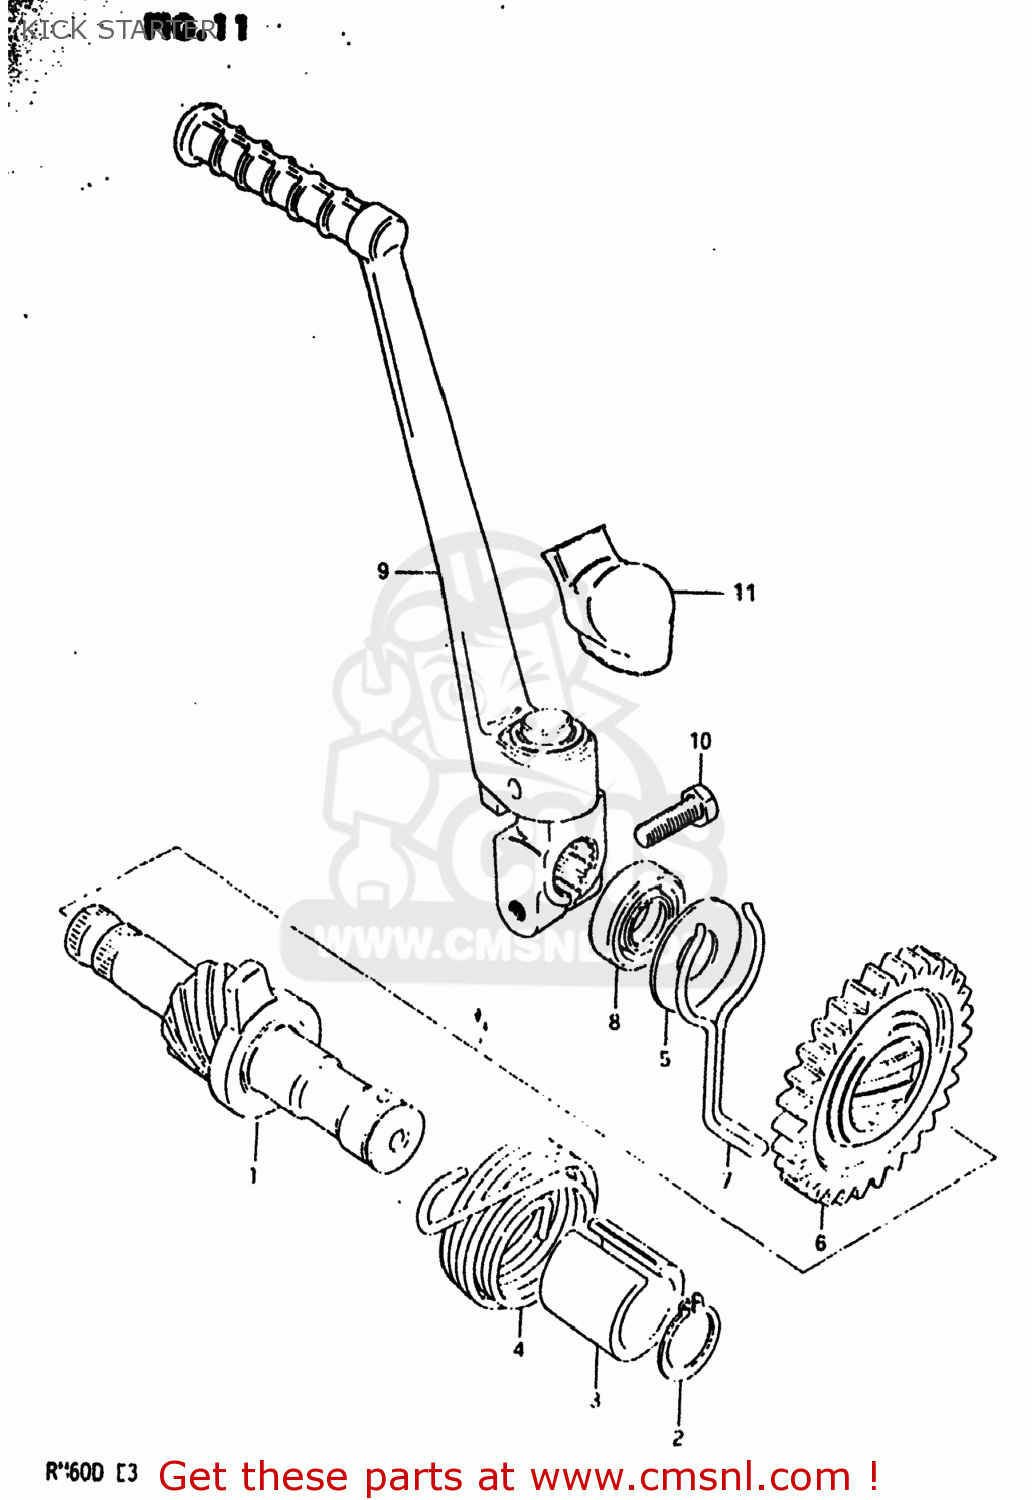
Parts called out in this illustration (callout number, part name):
1	SHAFT,KICK STARTER
2	CIRCLIP,16MM
3	GUIDE,KICK STARTER SFT SPRING
4	SPRING
5	WASHER
6	GEAR,KICK STARTER DRIVE(NT:30)
7	RETAINER,SNAP
8	SEAL,OIL(14X24X6)
9	LEVER ASSY,KICK STARTER
10	BOLT
11	COVER,KICK STARTER PEDAL
